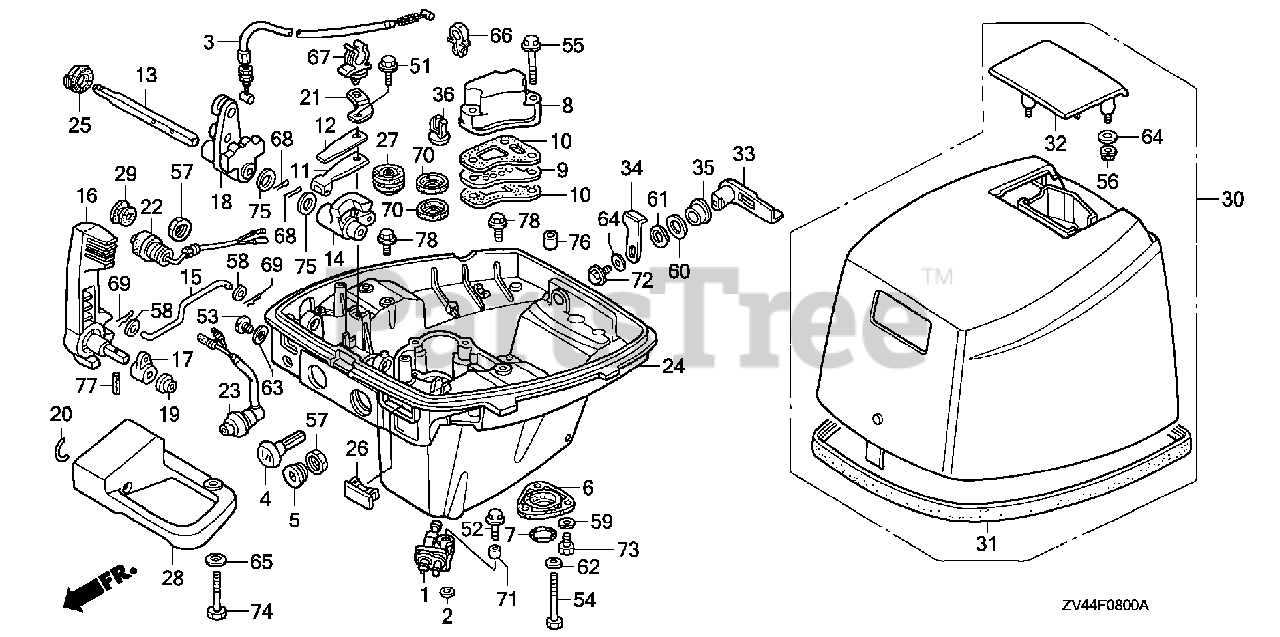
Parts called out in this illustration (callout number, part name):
1	CONNECTOR ASSY. B, FUEL
2	WASHER, PIVOT
3	CABLE, NEUTRAL STARTING
4	KNOB, CHOKE
5	GUIDE, CHOKE KNOB
6	PLATE, EX.
7	BAND, EX. SEAL
8	COVER, EX. CHAMBER *NH8* (DARK GRAY)
9	PLATE, EX. CHAMBER
10	GASKET, EX. CHAMBER
11	SPRING, CLICK
12	SPRING, CLICK ASSIST (NOT AVAILABLE)
12	SPRING, CLICK ASSIST
13	SHAFT, SHIFT
14	ARM, SHIFT
15	ROD, LINK
16	LEVER, SHIFT
17	LINK A, SHIFT
18	LINK B, SHIFT
19	BUSH, SHAFT
20	RUBBER, SHIFT SHAFT
21	BRACKET, WIRE HARNESS CLIP
22	SWITCH ASSY., STARTER
23	LAMP ASSY., INDICATOR
24	CASE, OIL *NH282MU* (OYSTER SILVER METALLIC-U)
25	GROMMET, OIL CASE (B)
26	GROMMET, OIL CASE (D)
27	GROMMET, OIL CASE (E)
28	HANDLE, CARRYING *NH282MU* (OYSTER SILVER METALLIC-U)
30	COVER, ENGINE *NH282MU* (OYSTER SILVER METALLIC-U)
31	SEAL, ENGINE COVER
32	HANDLE, TILT
33	LEVER, COVER LOCK *NH282MU* (OYSTER SILVER METALLIC-U)
34	HOOK, COVER LOCK
35	BUSH, COVER LOCK
36	GROMMET, WATER CHECK
51	BOLT, FLANGE (6X14)
52	BOLT, FLANGE (6X20)
53	BOLT, OIL CHECK (8X8)
54	BOLT, HEX. (6X40)
55	BOLT, FLANGE (6X35)
57	NUT, HEX. (16MM)
58	WASHER, PLAIN (5MM)
59	WASHER, PLAIN (6MM)
60	WASHER (14MM)
61	WASHER, WAVE (14MM)
62	WASHER, PLAIN (6MM)
63	WASHER, NYLON (8MM)
64	WASHER (6MM)
65	WASHER, PLAIN (8MM)
66	CLIP, ENGINE STOP SWITCH CORD
67	CLIP, WIRE HARNESS
68	PIN, SPLIT
68	PIN, SPLIT (2.0)
69	PIN, LOCK (5MM)
70	SEAL, WATER (14X26X6)
71	COLLAR, DISTANCE (6MM)
72	BOLT, HEX. (6X16)
73	BOLT, HEX. (6X16)
74	BOLT, HEX. (8X30)
75	WASHER, SHIFT
76	PIN A, DOWEL (8X14)
77	PIN, SPRING (4X22)
78	BOLT, FLANGE (6X16)
